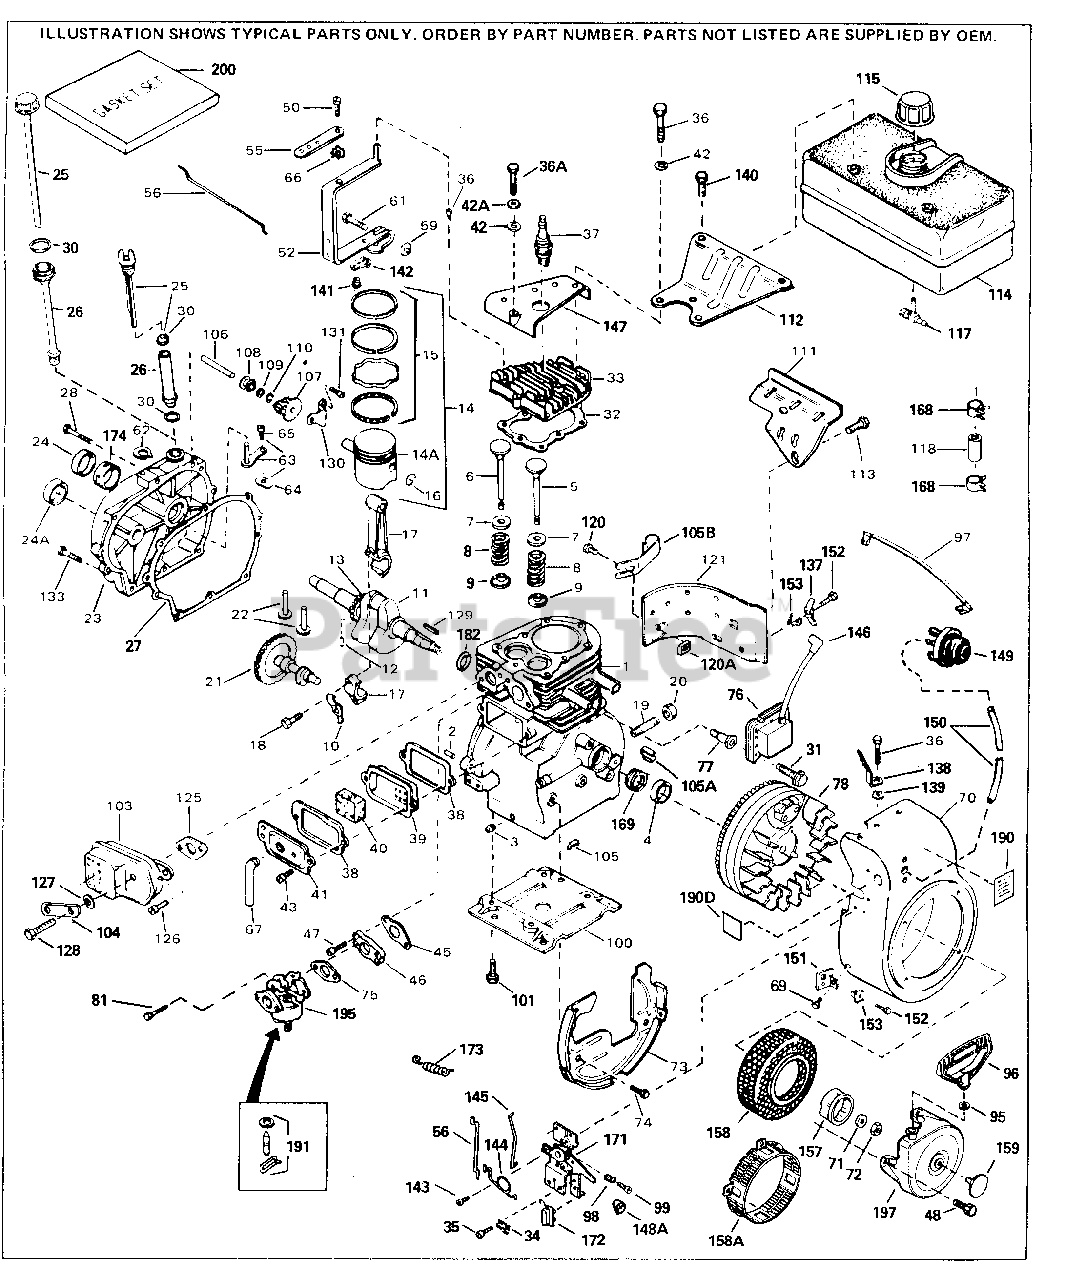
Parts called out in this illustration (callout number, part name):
1	"Cylinder (Incl. 2, 3 & 4) 2-3/4" Bor e
2	Dowel Pin
3	Oil Drain Plug (Sq. hd., 1/4-18)
4	Seal, Oil
5	Intake Valve (Std.) (Incl. 9)
5	Intake Valve (1/32" OS) (Incl. 9)
6	Exhaust Valve (Std.)(Incl. 151)
6	Exhaust Valve (1/32" OS) (Incl. 151)
7	Valve Spring Cap
8	Valve Spring
9	Cap, Lower valve spring
10	Dipper, Oil
11	Crankshaft
12	Pin, Crankshaft gear od.)
13	Gear, Crankshaft Used on early produc tion
14	Piston, Pin & Ring Set (Std.) 2-3/4" Bore
14	Piston, Pin & Ring Set (.010" OS)
14	Piston, Pin & Ring Set (.020" OS)
14A	Piston & Pin Ass'y. (Std.)(2-3/4") In cl. 16
14A	Piston & Pin Ass'y. (.010" OS) Incl. 16
14A	Piston & Pin Ass'y. (.020" OS) Incl. 16
15	Ring Set (Std.) (2-3/4" Bore)
15	Ring Set (.010" OS)
15	Ring Set (.020" OS)
16	Piston Pin Retaining Ring
17	Rod Assy., Connecting (Incl. 10 & 18)
18	Bolt, Connecting rod (2 each)
20	Cap, Oil drain
21	Camshaft (MCR)
22	Lifter, Valve
23	Cover, Cylinder (Incl. 24 & 106)
24	Oil Seal
25	Dipstick (Incl. 30)
26	Tube, Oil filler
27	* Gasket, Cylinder cover
28	Screw, 1/4-20 x 1-1/4"
30	"O" Ring
31	Screw, 1/4-20 x 5/8"
32	* Gasket, Cylinder head
33	Head, Cylinder
34	Conduit Clip
35	Screw, 10-32 x 3/8"
36	Screw, 5/16-18 x 2" (Use as required)
36	Screw, 5/16-18 x 2-1/4" Use as requir ed
36	Screw, 5/16-18 x 2-1/2" Use as requir ed
37	Spark Plug, Resistor (RJ17LM)
38	* Gasket, Breather
39	Breather Body
40	Breather Element
41	Valve Cover
42	Washer, Flat (Use as required)
42A	Washer, Belleville (Use as required)
43	Screw, 10-24 x 1/2"
45	* Gasket, Intake
46	Flange, Carburetor
47	Screw, 5/16-18 x 3/4"
48	Screw, 1/4-28 x 7/16"
50	Screw, 8-32 x 5/16"
52	Lever Assy., Governor
56	Link, Throttle
59	Lock Nut, 10-32
61	Screw, 10-32 x 3/4"
62	Retaining Ring
63	Rod, Governor (Incl. 64 & 65)
64	Yoke, Governor
65	Screw, 6-40 x 5/16"
66	Lock Washer #8
67	Breather Tube
69	Screw, T-40, 5/16-24 x 21/32"
70	Blower Housing (For elec.strt.) Incl. 134,135
71	Washer, Belleville
72	Nut, Hex
73	Blower Housing Baffle (Without electr ic starter knock-out) (Use as require d)
73	Blower Housing Baffle (With electric starter knock-out) (Use as required)
74	Screw, 1/4-20 x 5/8"
75	* Gasket, Carburetor
81	Screw, 1/4-20 x 27/32"
95	Washer, Flat
96	Starter Handle (Mitten Grip) also ava ilable in Packaged Part #740053B
97	Wire Assy., Ground
98	Spring, Compression
99	Screw, 5-40 x 7/16"
100	Base, Engine mounting
101	Screw, 5/16-18 x 3/4"
103	Muffler
105	Clip, Ground wire (Use as required)
106	Shaft, Mechanical governor
107	Gear Assy., Governor
108	Spool, Governor
109	WASHER
110	Retaining Ring
111	Bracket, Fuel tank mounting
112	Plate, Fuel tank mounting
113	Screw, 1/4-20 x 5/8"
114	Fuel Tank (Incl. 115 & 168) NOTE: Th ese tanks were built with different s ize fuel inlet openings. Tanks with t he 1-3/16" I.D. opening use fuel cap 33032 or 34210. Tanks with the 1-1/2 " I.D. opening use fuel cap 35355.
115	Fuel Cap (Red 1-1/2" ID) (also availa ble in Packaged Part #740005B) (Red Plastic) (Spurt Resistant, Low Profil e) (Use as required)
115	Fuel Cap (Red Plastic) (Spurt Resista nt, High Profile) (Use as required)
115	Fuel Cap (Red) ed)
115	Fuel Cap (White Plastic) (Std) Use as req.
117	Valve, Shut-off
118	Fuel Line (8.62") req.)
118	Fuel Line (Braided 32")(81 cm) Use as req.
120	Screw, 10-24 x 1/2"
121	Extension, Blower housing
125	* Gasket, Exhaust
126	Screw, 5/16-18 x 3/4"
128	Screw, 5/16-18 x 2"
129	Key, Flywheel
130	Bracket, Governor gear
131	Screw, 10-24 x 1/2"
133	Screw, 1/4-20 x 1-3/4"
140	Screw, 1/4-15 x 7/8"
141	Lock Nut, 8-32
142	Governor Lever Clamp
143	Screw, 10-32 x 1/2"
144	Spring, Speed control
145	Link, Governor
146	Cover, Spark plug (Use as required)
147	Cover Assy., Cylinder
149	Primer Assy.
150	Line, Primer
151	Bracket, Grommet mounting
152	Screw, 8-32 x 3/8"
153	Breather Tube Grommet
157	Cup, Starter
158	Starter Screen
168	Fuel Line Clamp
171	Control Bracket Incl. 98, 99, 144 & 1 72
172	Terminal Assy. (Use as required)
174	Bushing, Crankshaft
190	Decal, Primer
191	Inlet Needle, Seat & Clip Assy.
195	Carburetor (Incl. 75) (Refer to Divis ion 5, Section A, page 198 for breakd own)
197	Rewind Starter Refer to Division 5, S ection C, page 29 for breakdown
200	Gasket Set (Incl. items marked*)
